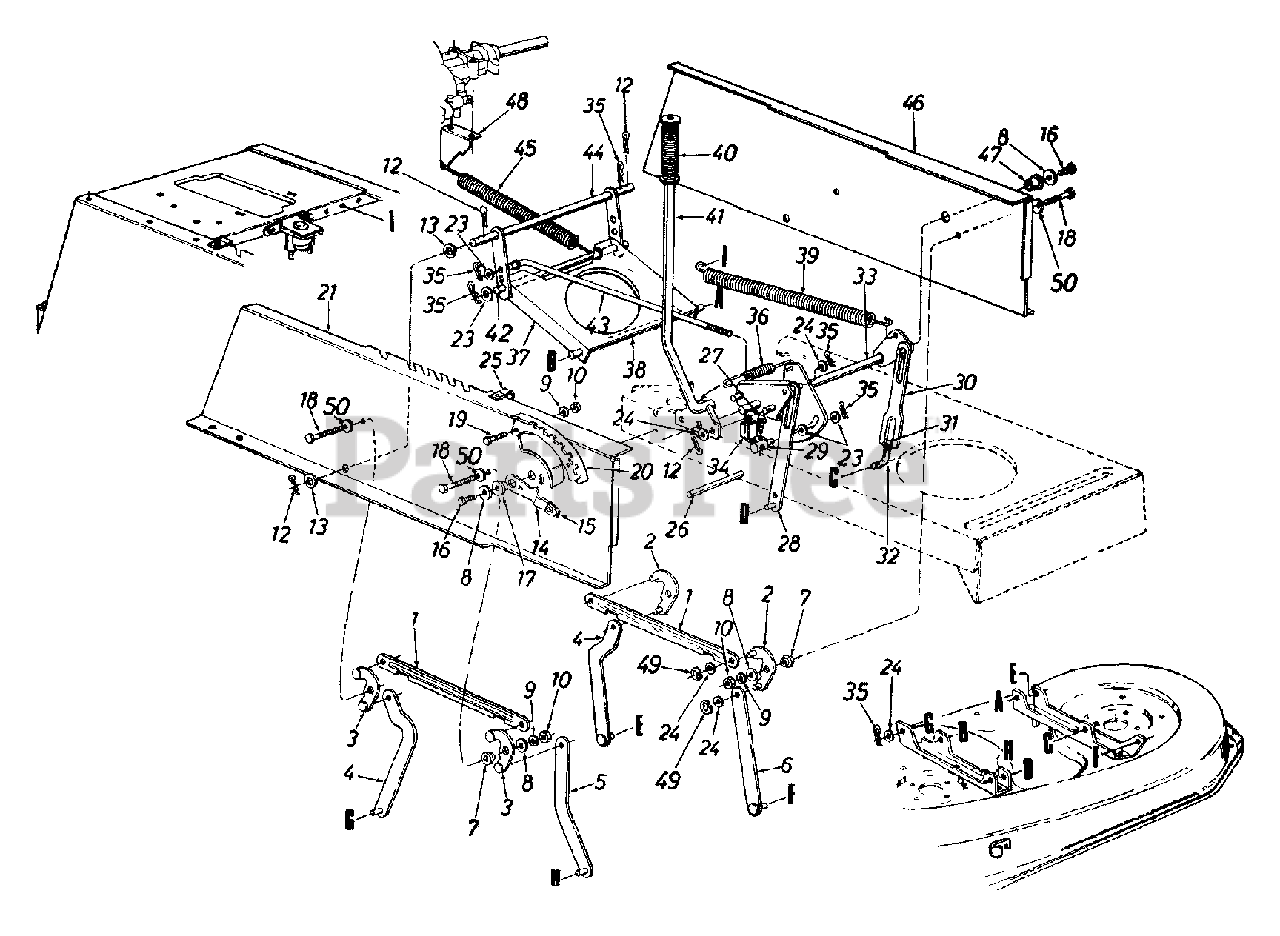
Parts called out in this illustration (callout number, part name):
3	Pivot Link Ass'y.-R.H.
7	Shld. Spacer .318" I.D.
8	Fl-Wash. .344" I.D. x .62" O.D.
9	L-Wash. 5/16" I.D.
10	Hex Nut 5/16-18 Thd. (Gr. 5)
12	Cotter Pin 1/8" Dia.
13	Fl-Wash. .635" I.D. x 1.0" O.D.
14	Height Adj. Stop Lever Ass'y.
16	Hex Wash. TT-Tap Scr.5/16-18 x
17	Flange Brg. .63" I.D.
18	Hex Wash. Hd. Scr. 5/16-18x .875" Lg.
19	Hex Bolt 5/16-18 x .75" Lg.
20	Index Brkt.
24	Fl-Wash. .531" I.D. x .93" O.D.
26	Running Board Rod
27	Hex Wash. Hd. Tap Scr.
31	Hex Nut 1/2-20 Thd. (Gr. 5)
32	Lift Link Adjuster
35	Inter. Cotter Pin 3/8" Dia.
36	Extension Spring
39	Extension Spring
40	Grip (Lift Handle)
41	Deck Lift Handle Ass'y.
42	Shaft 3/8" Dia. x 9.34" Lg.
43	Disengagement Rod
44	Stabilizer Shaft Ass'y.
45	Extension Spring 7.58" Lg.
49	"E"-Ring
50	Bell-Wash. .325" I.D.
